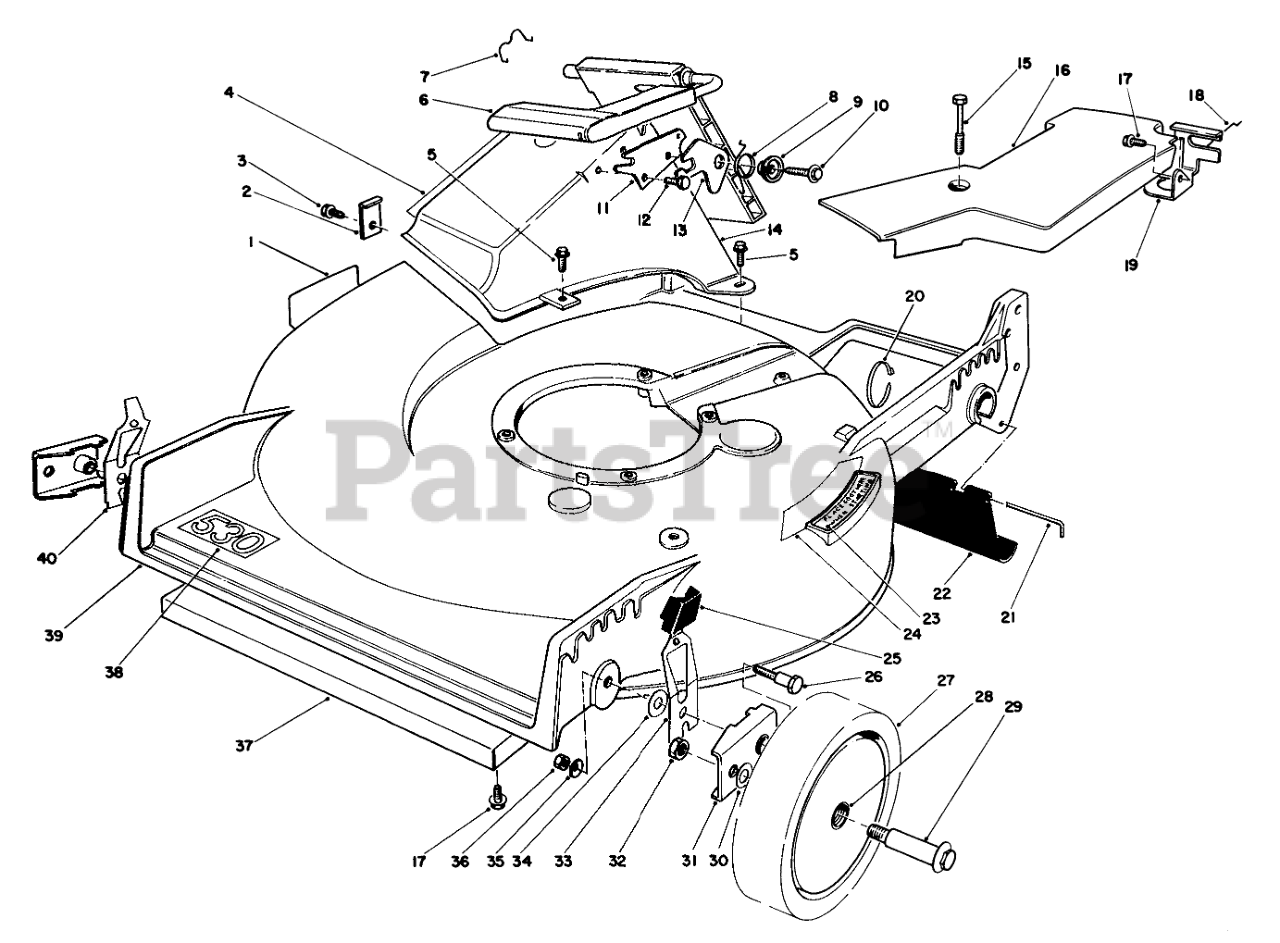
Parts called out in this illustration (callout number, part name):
1	DECAL-DANGER
2	TUNNEL CLIP
3	SCREW
4	ATTENTION DECAL
5	SCREW-HWH
6	Discharge Door Assembly
7	DOOR RET SPRING
8	TORSION SPRING
9	DOOR SPACER
10	SCREW-HWH
11	DOOR LATCH PLATE
12	SCREW-PLASTITE
13	SAFETY LATCH
14	Tunnel Discharge
15	SCREW-HHFTF
16	Cover-Belt
17	SCREW-HWHTF
18	RETAINER-CABLE
19	Bracket-Traction Adj.
20	TIE-CABLE
21	ROD-SHIELD
22	SHIELD-TRAILING
23	STEP PAD DECAL
24	Decal-Place Foot Here
25	KNOB-ARM
26	PIVOT SCREW
27	Wheel & Tire Assy. (Incl. Ref. #28)
28	BUSHING
29	BOLT-WHEEL
30	WASHER
31	HP PIVOT ARM ASM
32	Nut
33	L. HP SPRING ARM ASM
34	WASHER-PIVOT
35	WASHER-BELLEVILLE
36	NUT-LOCK, NI
37	Shield-front
38	Decal-530
39	21 SP RB HSG/DECAL
40	R HP SPRING ARM ASM
